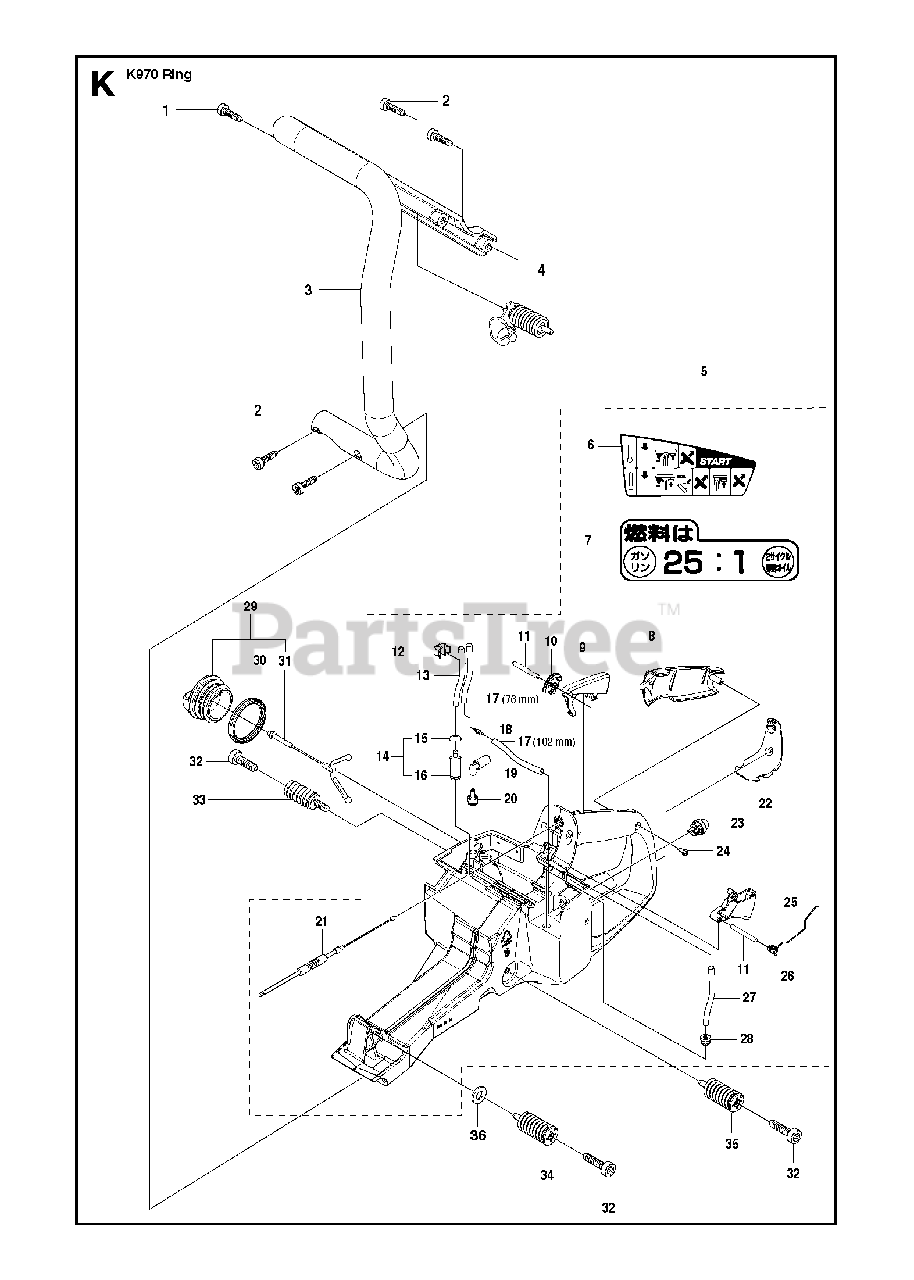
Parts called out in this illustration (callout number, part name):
1	SCREW ITXSCM
2	SCREW ITXSCT
4	ANTIVIBRATION ELEMENT
5	FUEL TANK ASSYIncl. 6 - 28
9	THROTTLE LOCKOUT
11	PARALLEL PIN
13	FUEL HOSE300 mm
14	FUEL FILTERIncl. 15 - 16
17	FUEL HOSE190 mm
19	HOLDER ASSY
20	TANK VENT ASSY
21	THROTTLE CABLE ASSY
22	GROUND SUPPORT
24	SCREW CITXPANT
25	THROTTLE CONTROL
27	FUEL HOSE70 mm
28	BUSHING
29	TANK CAP ASSYIncl. 30 - 31
32	SCREW ITXSCM
33	ANTIVIBRATION ELEMENT
34	ANTIVIBRATION ELEMENT
35	ANTIVIBRATION ELEMENT
